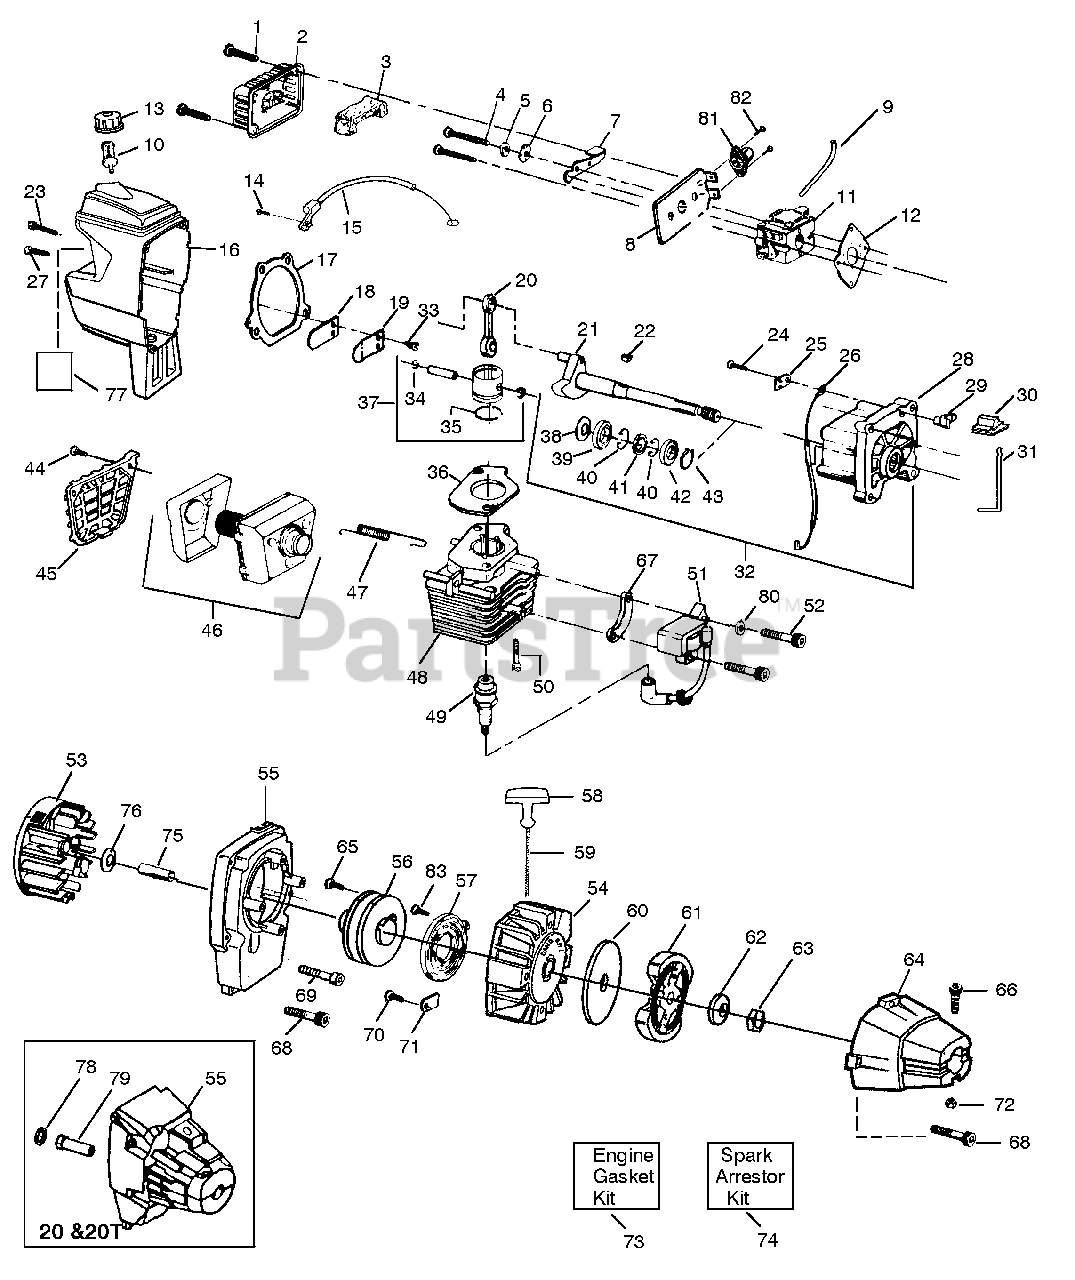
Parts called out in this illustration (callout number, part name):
2	Air Filter Cover
3	Air Filter
6	Wave Washer
7	Choke Shutter
8	Air Filter Plate (Type 1)
8	Air Filter Plate (Type 2 & 3)
9	Fuel Line Kit (Fuel LineType 1)
9	Fuel Line Kit (Return LineType 2 & 3)
10	Fuel Pickup Ass'y.
10	Carburetor (40, 40T, 50, 50T (WA199) Type 1)
12	Carburetor Gasket
13	Fuel Cap Ass'y.
14	Throttle Cable Ass'y. (40, 40T, 50, 50T-Type 1)
16	Shroud & Tank Ass'y. (Type 1)
16	Shroud & Tank Ass'y. (Type 2 & 3)
17	Crankcase/Shroud Gasket
19	Reed Stop
19	Connecting Rod Ass'y. (40T, 50, 50T)
19	Crankshaft Ass'y. - See Service Ref. 2 (40, 40T, 50, 50T)
22	Flywheel Key
25	Switch Insulator
26	Lead Wire
28	Crankcase Ass'y.
29	Switch Ramp
30	Switch Button
31	Switch Spring
31	Crankcase & Crankshaft Ass'y (40, 40T, 50, 50T)
34	Piston Pin Retainer
34	Piston Ring (40T, 50, 50T)
36	Cylinder Gasket
36	Piston Kit (40T, 50, 50T)
39	Inner Bearing
40	Retaining Ring
41	Crankshaft Seal
42	Outer Bearing
43	Crankshaft Retaining Ring
45	Muffler Guard
46	Muffler Kit
47	Muffler Attachment Spring
47	Cylinder (40T, 50, 50T)
49	Spark Plug
50	Screw (20, 20T, 50)
51	Ignition Module Kit
51	Flywheel Ass'y. (20, 40, 40T, 50, 50T)
54	Pulley Housing Ass'y. 40, 40T, 50, 50T
54	Fan Housing (40, 40T, 50, 50T)
56	Starter Pulley Kit
57	Starter Spring
58	Starter Handle
59	Rope Kit
60	Clutch Washer- 40, 40T, 50, 50T
61	Clutch Ass'y. Kit- 40, 40T, 50, 50T
62	Washer40, 40T, 50, 50T
63	Nut-40, 40T, 50, 50T
64	Clutch Housing-40, 40T, 50, 50T
65	Screw-Rope Retaining
71	Retainer
73	Engine Gasket Kit
74	Spark Arrestor Kit
75	Spacer 40, 40T, 50,, 50T
76	Washer
77	Instruction Decal (Type 1)
77	Instruction Decal (Type 2)
77	Instruction Decal (Type 3)
81	Primer Bulb Ass'y. Type 2 & 3
82	ScrewPrimer Type 2 & 3
83	ScrewStarter Spring Type 3
